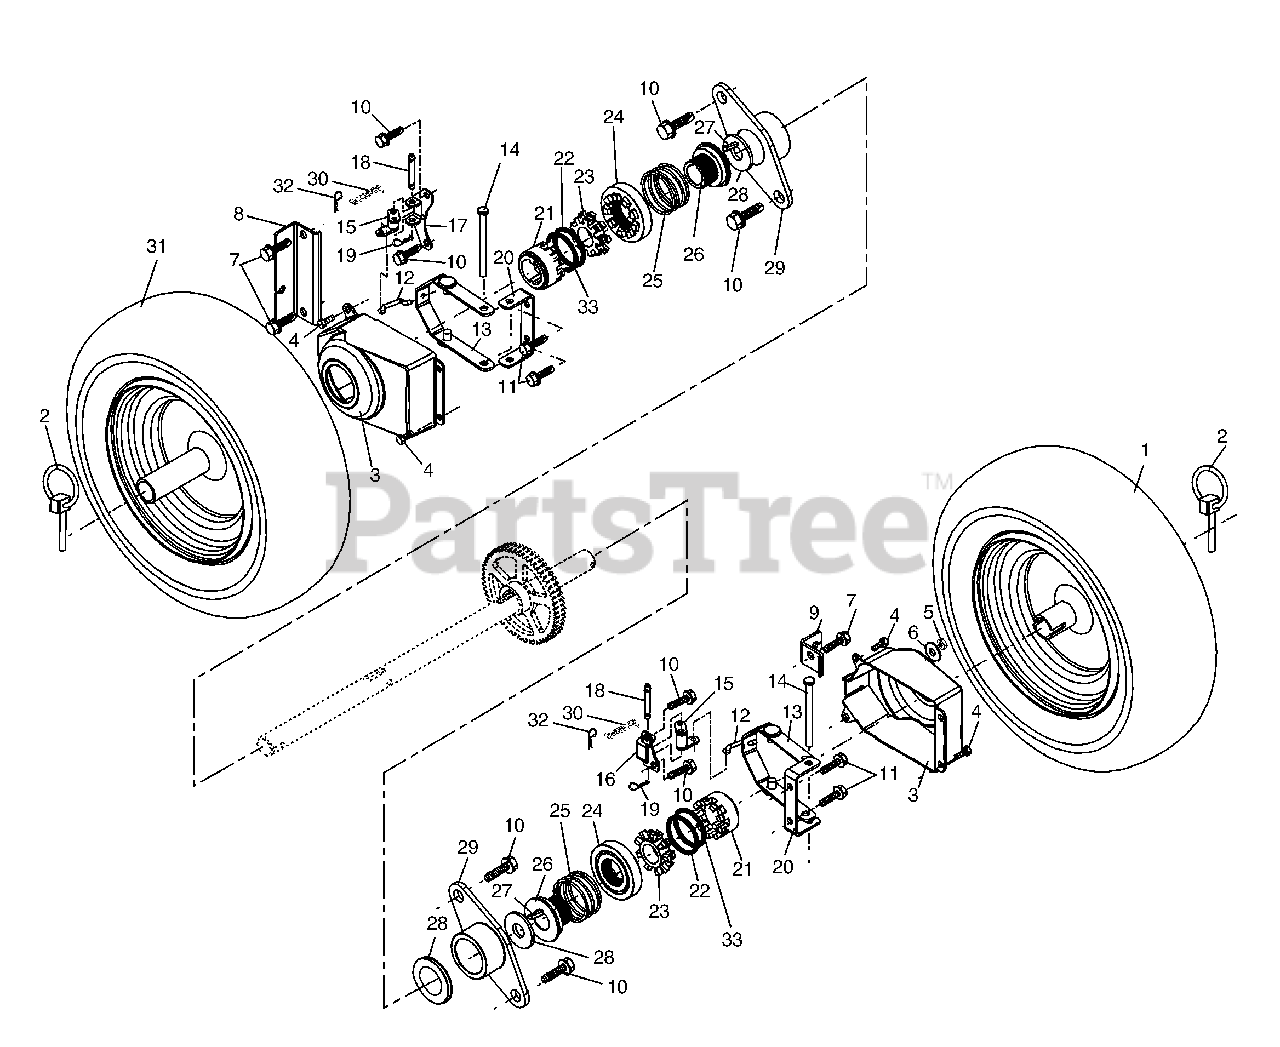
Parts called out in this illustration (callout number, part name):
1	Wheel Assembly, 16", Power Steering, LH
2	Pin, Klik 1/4
3	Cover, Power Steering
4	Shoulder Bolt, Hex Head #10-24 x 1/2
5	Nut, Lock 5/16-18
6	Washer, Flat 5/16
7	Screw, Hex Head 3/8-16 x 1
8	Bracket, Steer Cable RH
9	Bracket, Steer Cable LH
10	Screw, Hex Head 5/16-18 x 5/8
11	Screw, Hex Head 5/16-18 x 1/2
12	Link, Steering Lever
13	Lever Assembly, Steering
14	Pin, Steering Lever
15	Bellcrank Assembly
16	Bracket Assembly, LH Steering
17	Bracket Assembly, RH Steering
18	Pin, Steering Bellcrank
19	Retainer, Hairpin
20	Bracket, Lever Assembly
21	Driver, Wheel
22	Ring, Wire Retainer
23	Lobe, Wheel
24	Slide, Clutch
25	Spring, Clutch Slide
26	Lobe, Axle
27	Key, Square 1/4
28	Washer, Thrust (1")
29	Bearing, Axle
30	Spring, Return
31	Wheel Assembly, 16", Power Steering, RH
32	Clip, Retainer
33	Ring, Retaining
